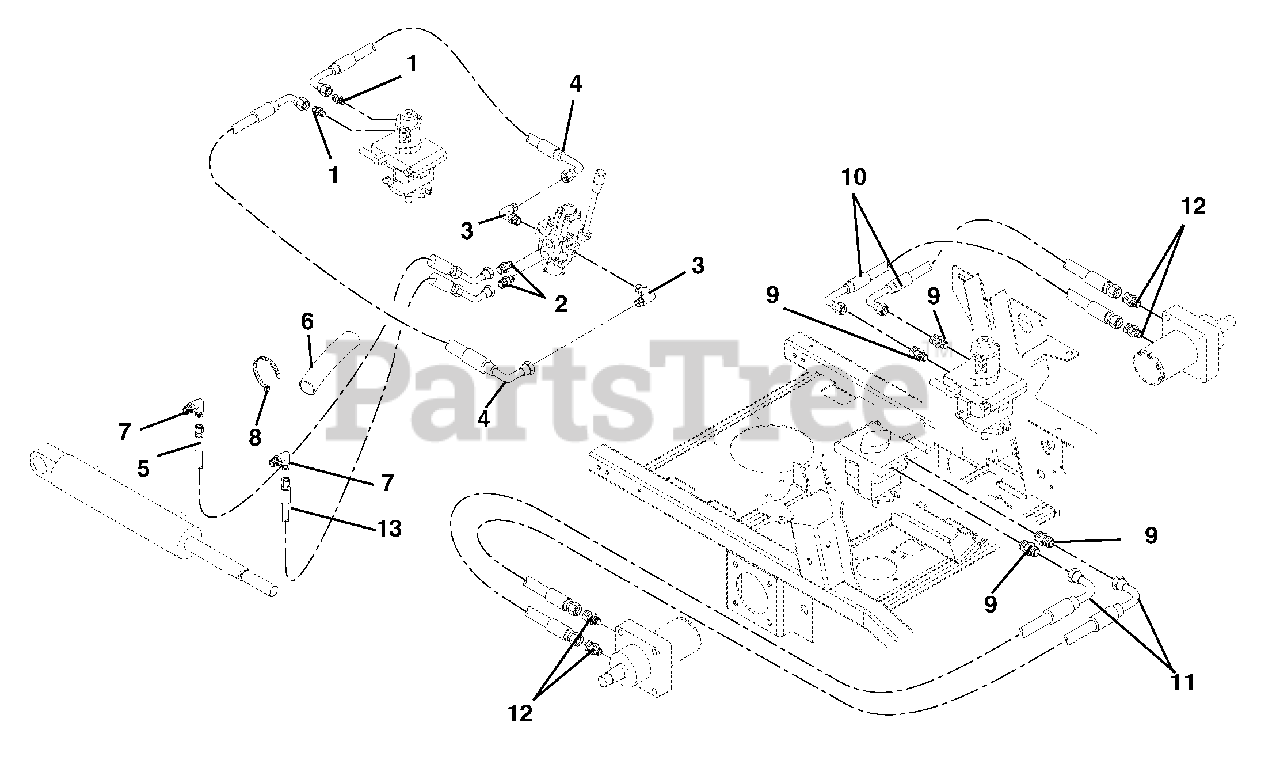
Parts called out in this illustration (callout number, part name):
1	Fitting, Hydraulic
2	Fitting, Hydraulic
3	Fitting, Hydraulic Elbow
4	Hose, Hydraulic
5	Hose, Hydraulic
6	Sleeve, Protective 24"
7	Fitting, Hydraulic Elbow
8	Cable Tie
9	Adapter, Hydraulic
10	Hose, Hydraulic
11	Hose, Hydraulic
12	Adapter, Hydraulic
13	Hose, Hydraulic
